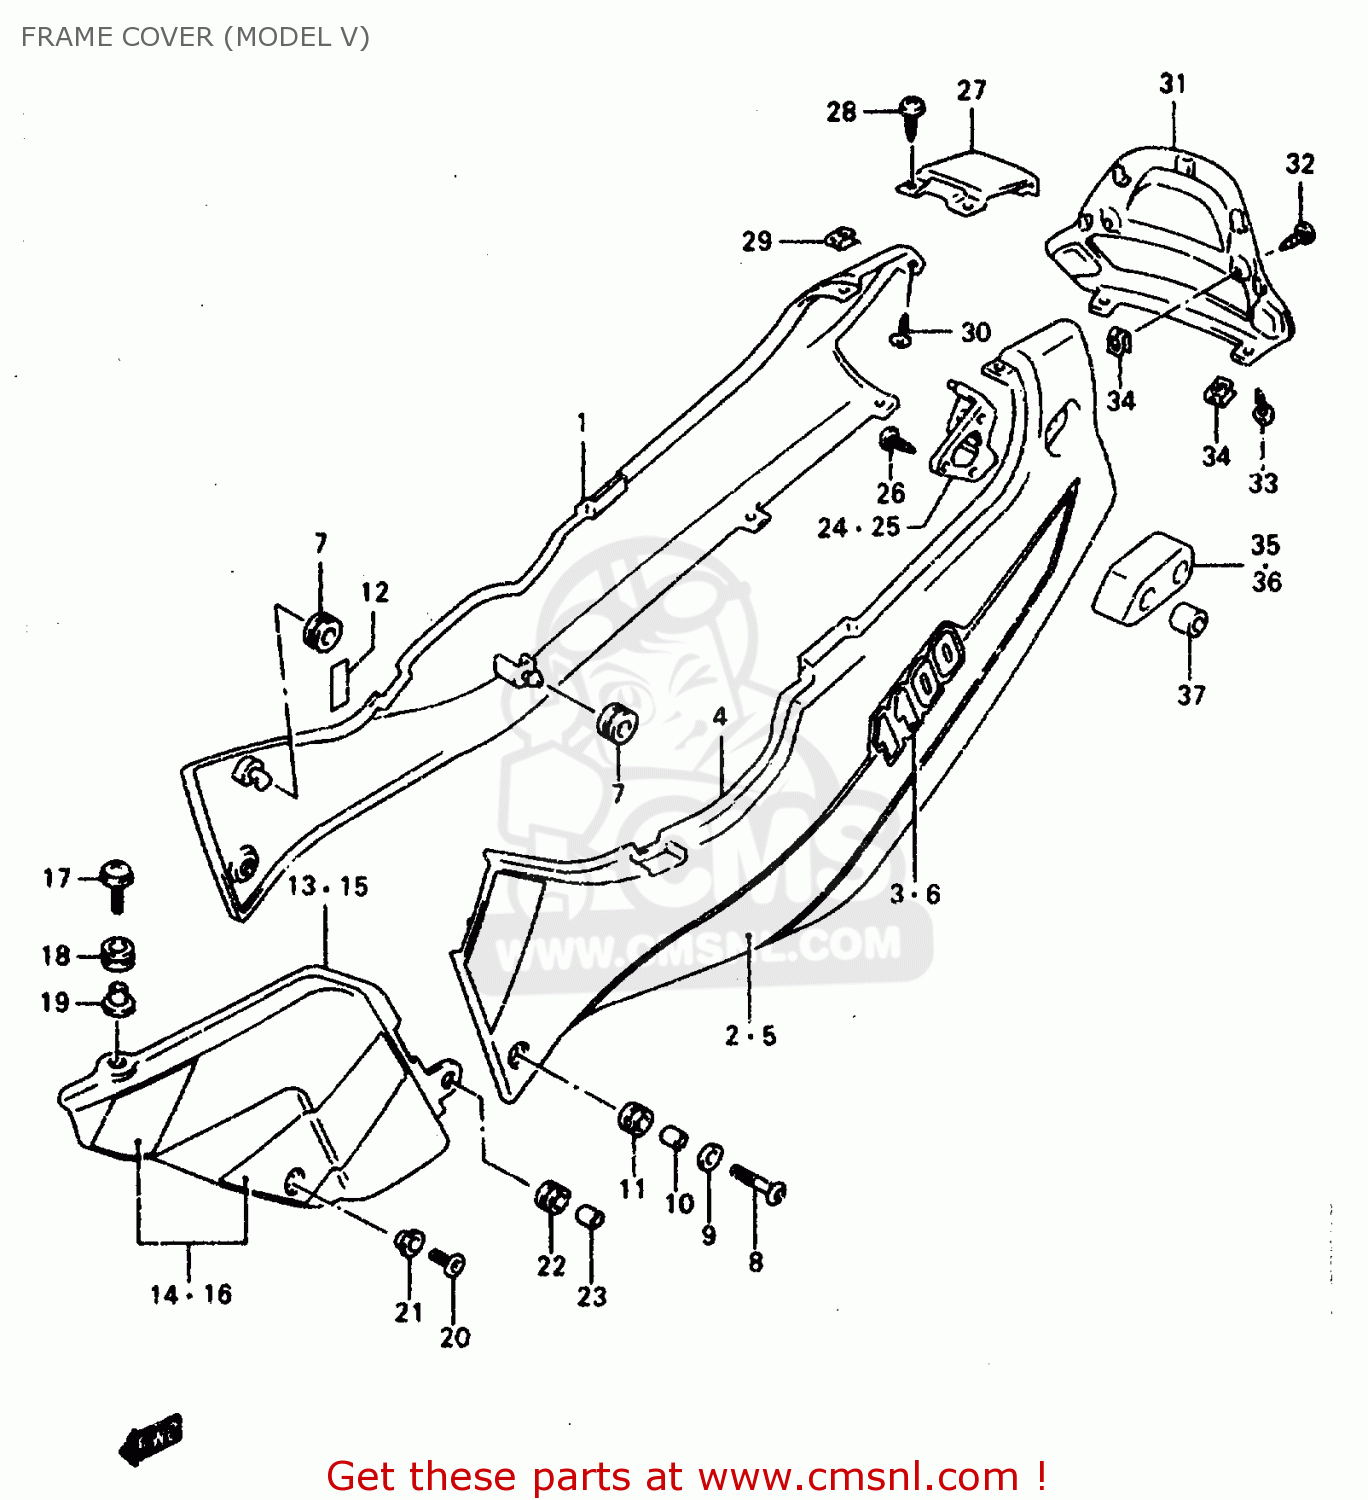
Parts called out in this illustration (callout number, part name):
1	COVER ASSEMBLY,FRAME,RIGHT
2	TAPE SET,FRAME COVER,RIGHT
3	EMBLEM,FRAME COVER,R
4	COVER ASSY,FRAME,L(WHITE)
5	TAPE, FRONT LH
6	EMBLEM,FRAME COVER,L
7	CUSHION
8	SCREW(6X30)
9	WASHER
10	SPACER(6.5X9X9)
11	CUSHION
12	CUSHION
13	COVER ASSY,FRAME BODY,R
14	TAPE SET,FRAME COVER B
15	COVER ASSY,FRAME BODY,L
16	TAPE SET,FRAME COVER B
17	SCREW(6X25)
18	CUSHION
19	WASHER
20	SCREW(5X14)
21	WASHER
22	CUSHION
23	SPACER(6.5X9X9)
24	BRACKET,RR COMBINATION LAMP,L
25	BRACKET,RR COMBINATION LAMP,L
26	SCREW
27	COVER ASSY,FRAME CTR
28	NUT
29	NUT
30	SCREW
31	SCREW(5X12)
32	SCREW 5X12
33	NUT
34	NUT
35	SPACER (8.5X16X37)
36	CUSHION,PILLION RIDER HANDLE,L
37	SPACER (8.5X16X37)
45	SPACER (8.5X16X37)
